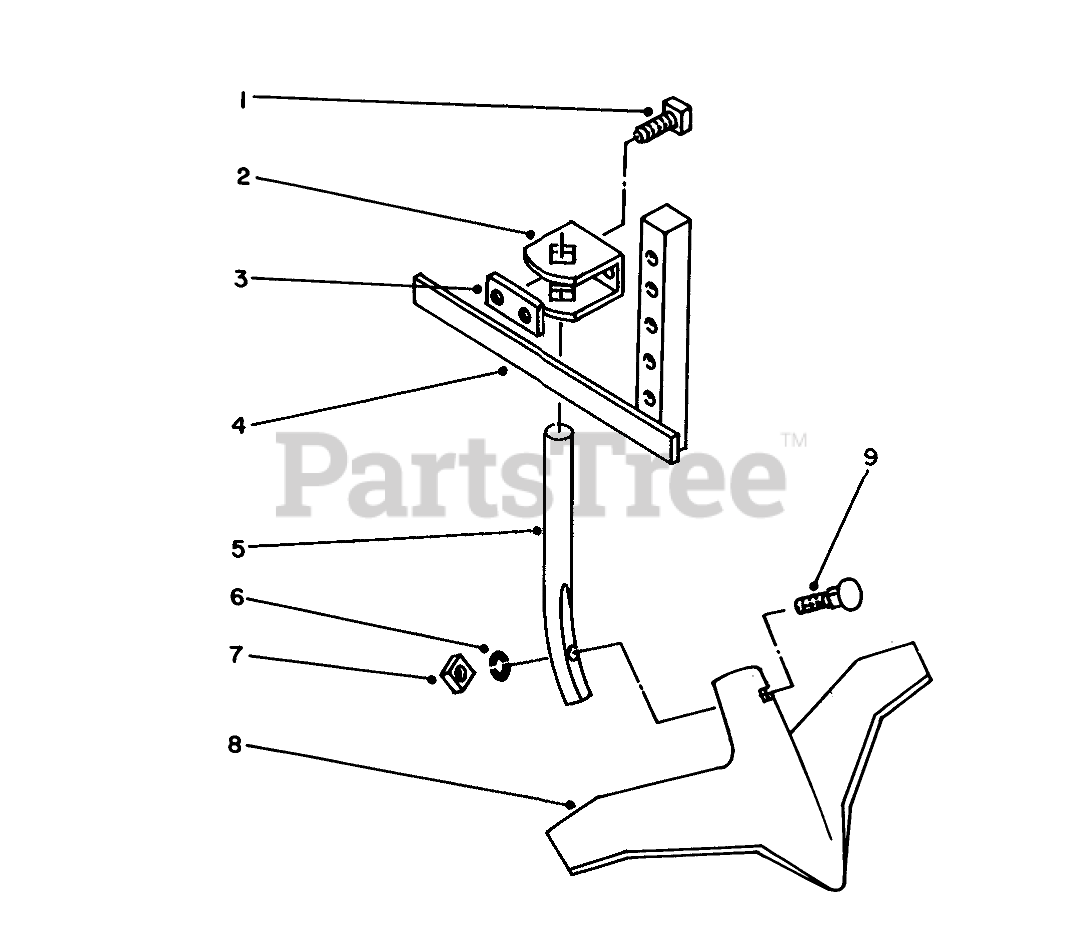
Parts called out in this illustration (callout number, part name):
1	Set Screw
2	Clamp
3	Special Nut
4	Hitch
5	Attachment Standard
6	WASHER-LOCK
7	Square Nut
8	15" Sweep
9	Plow Bolt
